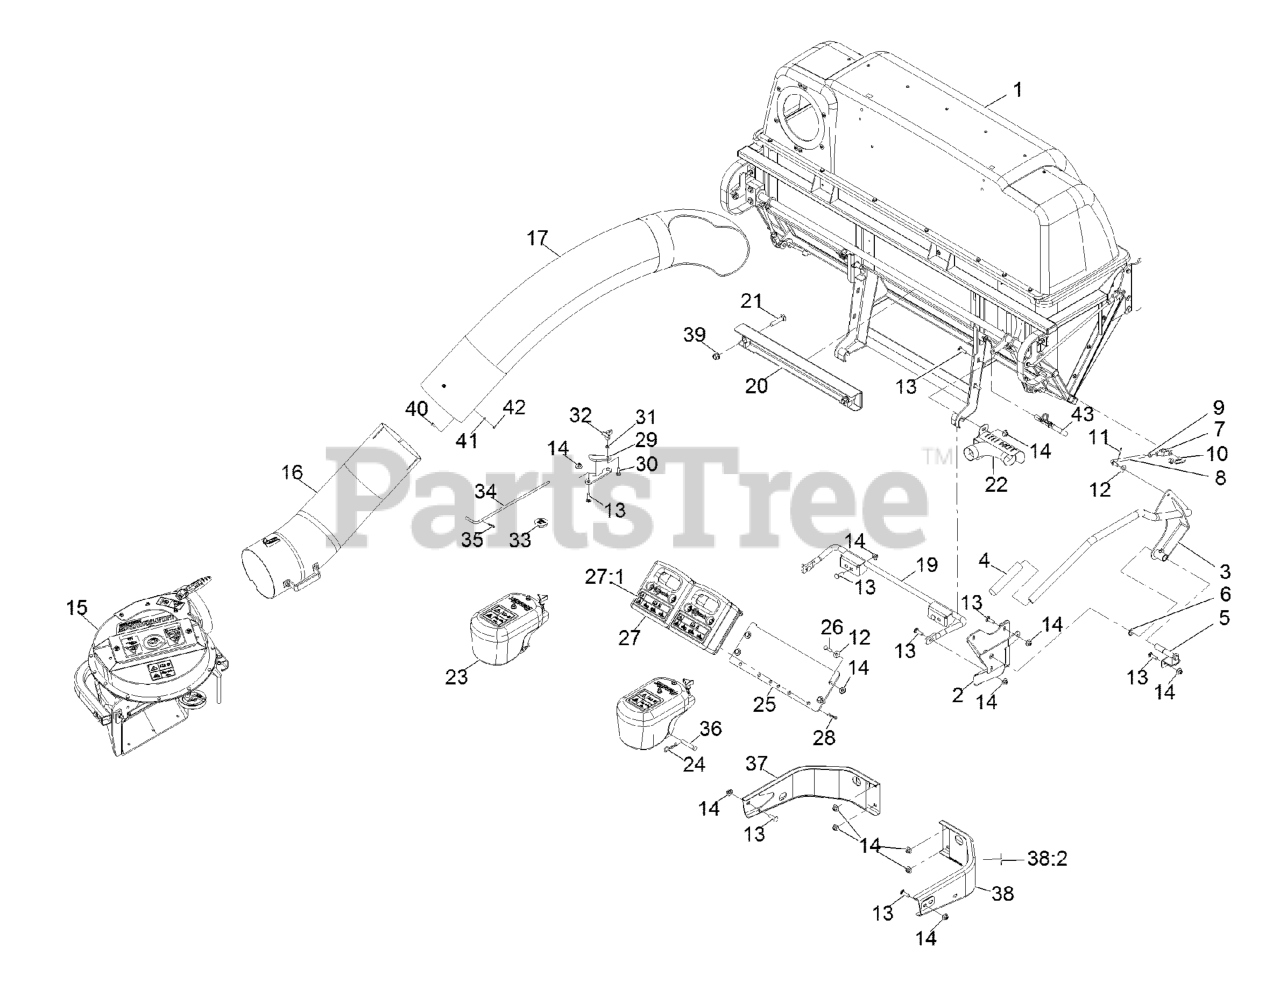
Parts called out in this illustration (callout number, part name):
1	ASM,Hopper Lg Qds
2	MOUNT-PIVOT
3	WLD,DUMP HANDLE
4	HANDLE-GRIP
5	PIN-HANDLE
7	YOKE-LINKAGE, BRAKE
8	LINK-HANDLE
9	NUT-HEX
10	PIN-SPRING, CLEVIS
11	PIN-COTTER
12	WASHER-FLAT
13	Bolt-Carriage 3/8-16 X 1 1/4
14	Nut-Nyloc 3/8-16 Flg
15	ASM, BLOWER LARGE - SVC ONLY
16	LOWER TUBE ASM
17	TUBE-UPPER
19	MOUNT-BAGGER, LOWER
20	MOUNT-BAGGER, UPPER
21	SCREW-CARR
22	EXHAUST DIVERTER ASM
23	ASM,CASTER WEIGHT
24	PIN-COTTER
25	PLATE,WEIGHT ASM MOUNT
26	SCREW-HH
27	ASM,CAST WEIGHT
27:1	DECAL-WARNING WEIGHT
28	PIN-HAIR
29	BRACKET,BELT COVER
30	BOLT-CARR
31	RING-RETAINING, BOLT
32	KNOB-3 PRONG
33	PLUG, BLACK NYLON 1.75
34	PIN,CHUTE PIVOT
35	PIN-COTTER
36	PIN-CLEVIS
37	BUMPER-RH
38	LH BUMPER ASM
38:2	DECAL-WARNING
39	Nut-Lock 1/2-13
40	SCREW-HWH
41	WASHER-FLAT
42	NUT-LOCK, NI
43	PIN-MOUNT, BAGGER
